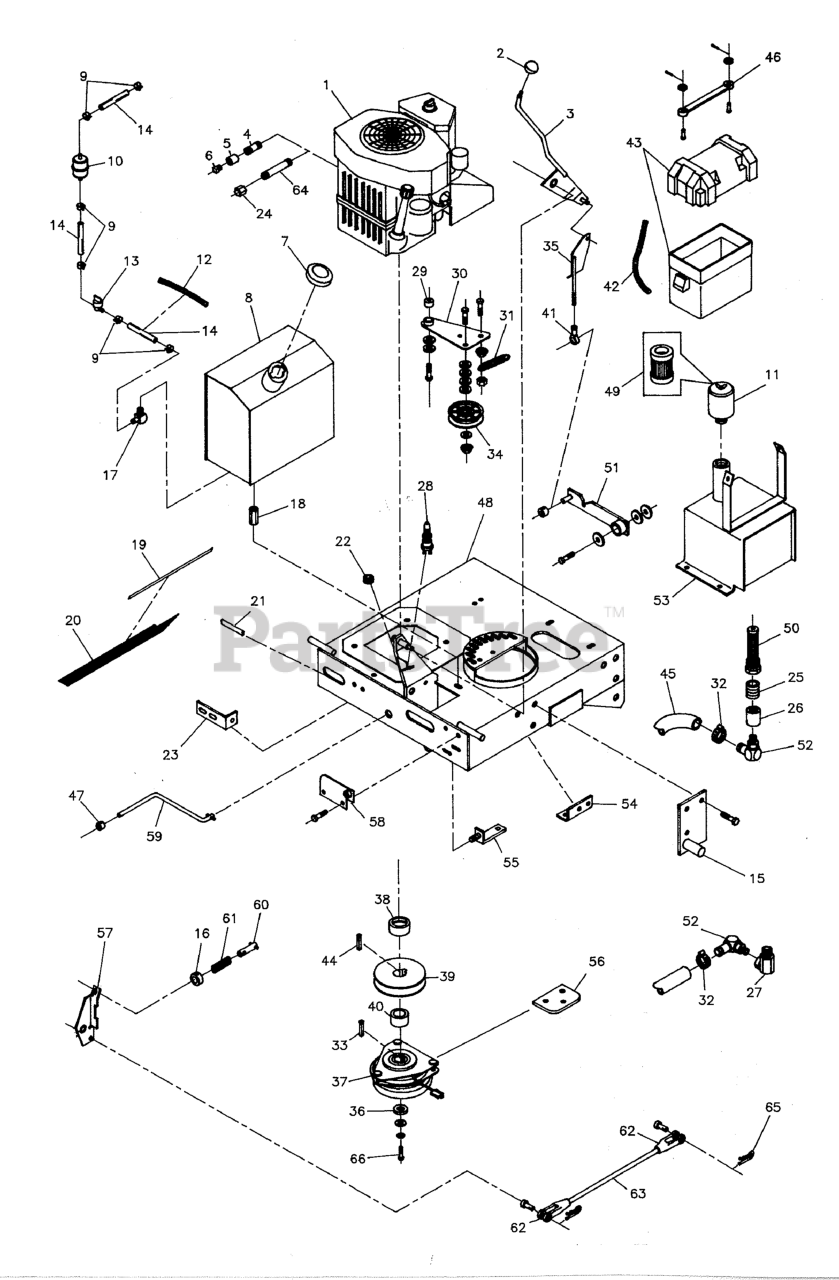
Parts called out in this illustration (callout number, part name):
2	Black Knob
3	Brake Lever Weldment
4	Pipe Nipple
5	Coupler
6	Pipe Plug
8	Fuel Tank Assembly
9	CLAMP, Hose
10	FUEL FILTER
11	Air Filter Assembly
12	WIRE LOOM, 16"
13	VALVE, Fuel Shut-Off
14	1/4" Fuel Line, 24" Long
15	Pivot Bracket - RH
16	COLLAR, 5/8" Set
17	Brass Fitting
18	Coupling Nut
19	Body Molding 13" Long
20	Grass Screen
21	BLACK SOFTONE Q-TRIM, 3.25" LONG
22	GROMMET, 1/2"
23	CABLE BRACKET
24	CAP, 3/8 NPT
25	NIPPLE, 1/2" NPT Close
26	COUPLER, 1/2" NPT
27	FITTING, 1/2 NPT Swivel, 90 Deg.
28	SWITCH, Plunger, NO
29	SPACER, .32 x .75 x 1.06
30	IDLER ARM ASSEMBLY, Complete
31	SPRING, Extension
32	CLAMP, #10 Hose
33	KEY, 1/4 SQ. X 1
34	IDLER PULLEY
35	BRAKE LOCK LINK
36	SPACER, .45 x 1.62 x .37
37	CLUTCH, Electric, 1" Shaft
37	CLUTCH, Electric, 1-1/8" Shaft
38	CRANKSHAFT SPACER
38	SPACER, 1.13 X 1.75 X .88
39	PULLEY, Crankshaft
40	SPACER, 1.00 X 1.75 X .38
40	SPACER, 1.13 X 2.00 X .37
41	BALL JOINT 5/16-24 RH FEMALE BRONZE RACE
42	WIRE LOOM, 24"
43	BOX, Battery
44	KEY, 1/4 SQ. X 1
45	Inlet Hose
46	RUBBER STRAP
47	COLLAR, 5/16" Set
48	ENGINE DECK
49	Air Filter Element
50	STRAINER
51	NEUTRAL LOCK LEVER, Complete
52	FITTING, 90 Degrees 1/2" NPT
53	HYDRO TANK WELDMENT
54	Plate Bracket
55	Spring Anchor
56	CLUTCH ANCHOR PAD
57	BRAKE ROCKER ARM
58	Fuel Tank Mount Plate
59	Dump Valve Rod Assembly
60	SPRING BAR ASSEMBLY
61	SPRING, Compression
62	CLEVIS, 5/16-24, Plastic
63	BRAKE LINKAGE ROD
64	NIPPLE, 3/8 NPT X 4-1/2
65	HAIRPIN CLIP
66	CRANKSHAFT BOLT, 7/16 x 3
